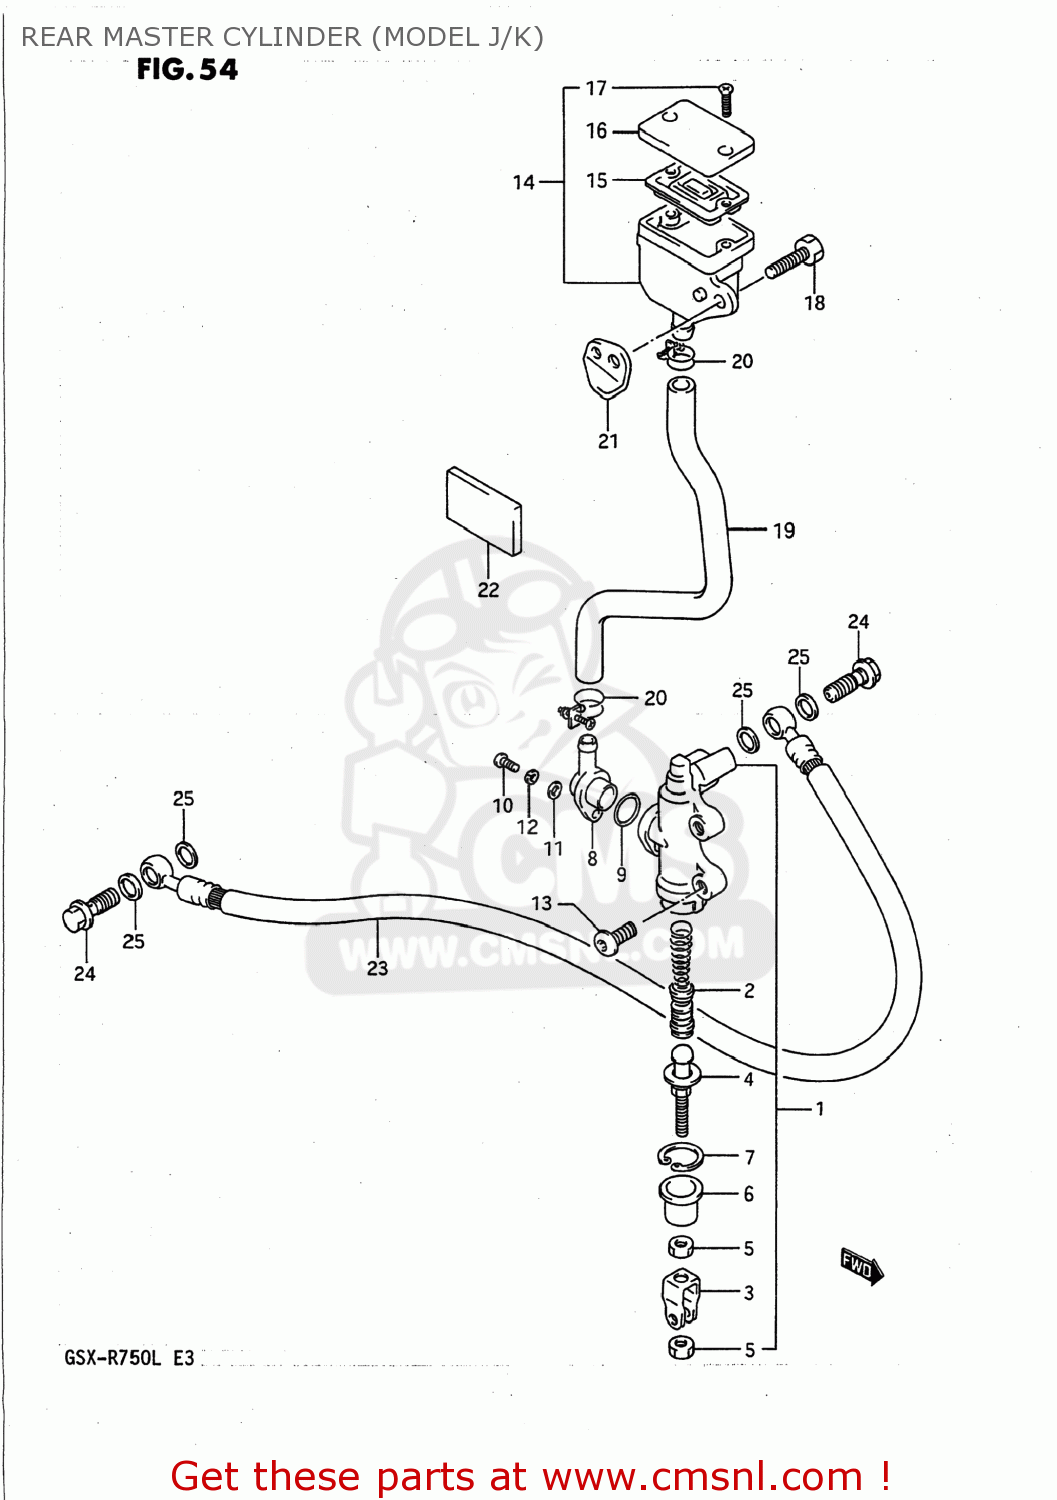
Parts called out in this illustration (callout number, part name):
1	CYLINDER ASSEMBLY,REAR MASTER
2	PISTON/CUP SET
3	YOKE
4	ROD,PUSH
5	NUT
6	BOOT
7	CIRCLIP
8	CONNECTOR
9	O RING
10	SCREW
11	WASHER
12	LOCK WASHER
13	SCREW(8X16)
14	TANK ASSEMBLY,RESERVOIR
15	DIAPHRAGM
16	CAP
17	SCREW
18	BOLT
19	HOSE,RESERVOIR TANK
20	CLAMP
21	BRACKET,RESERVOIR TANK RR
22	CUSHION,PANEL
23	HOSE,RR BRAKE
24	BOLT UNION
25	WASHER(10X15X1.5)
